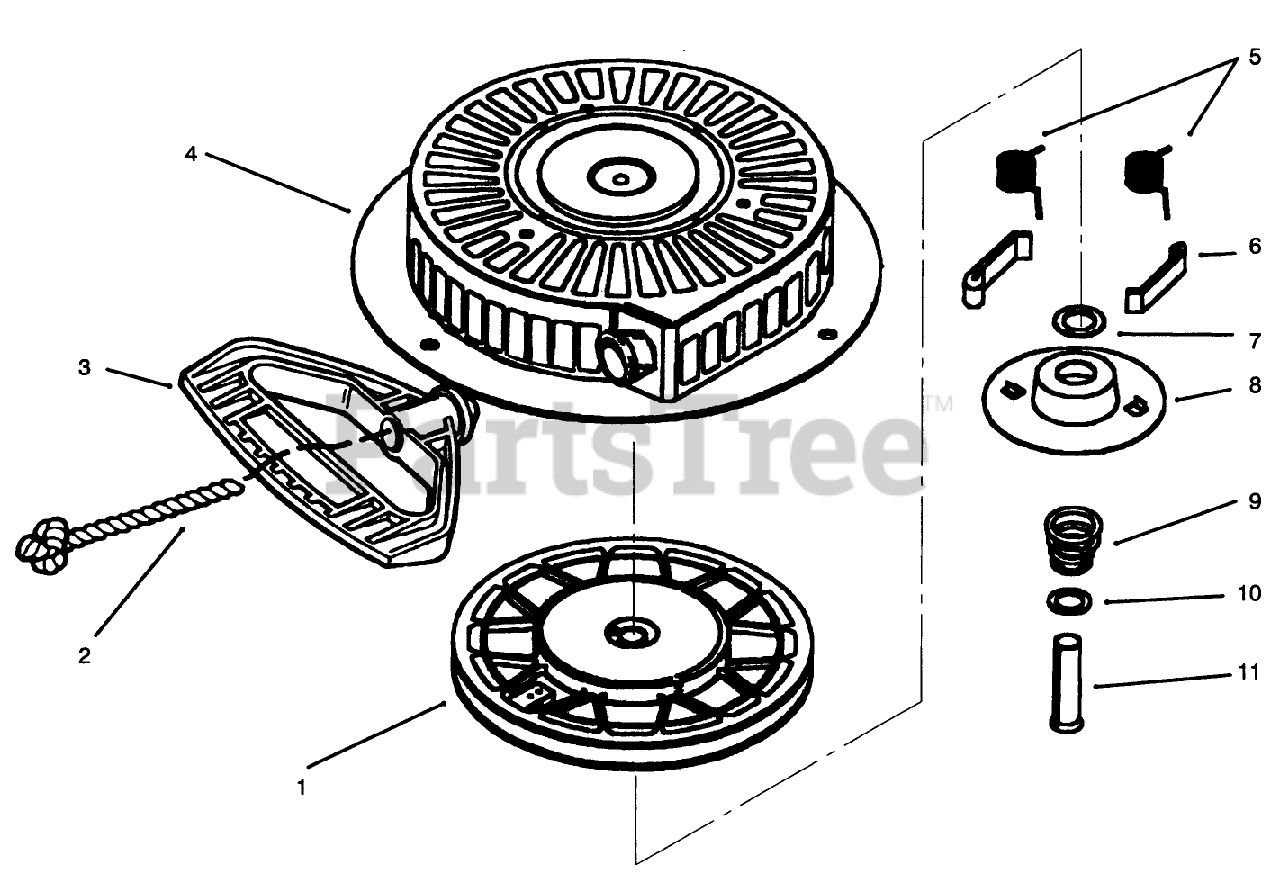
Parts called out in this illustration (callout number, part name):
1	Pulley and Rewind Spring ASM
2	Rope-Starter (98 cut to length)
3	Handle-Starter, Mitten Grip
4	Spring, Pawl
5	Spring-Dog
6	Dog-Starter
7	Washer
8	Retainer
9	Spring-Brake
10	Washer
11	Pin, Spring (Incl. Ref. #7)
